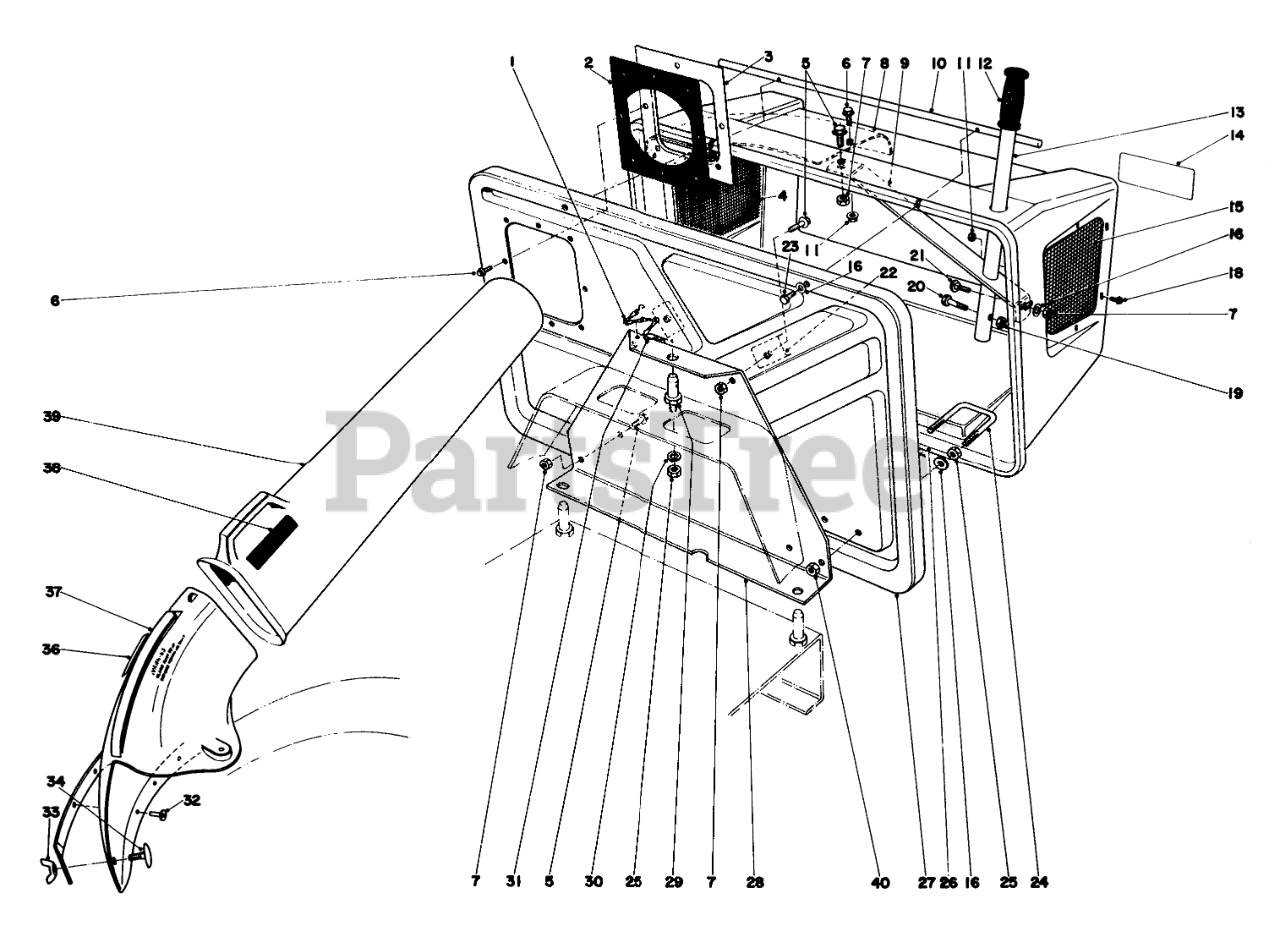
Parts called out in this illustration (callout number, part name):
1	6-LINK CHAIN W/HOOK
2	INLET SEAL
3	FRAME SEAL
4	Screen
5	SCREW-HHF
6	SCREW
7	NUT-HEX, SIDE DEFORM
8	DEFLECTOR
9	HANDLE GUIDE
10	PIVOT ROD
11	NUT-LOCK, FLANGE
13	HANDLE TUBE
14	EASY EMPTY BAG DECAL
15	SCREEN
16	WASHER-FLAT
18	SCREW-HWH
19	NUT-HEX, SIDE DEFORM
20	SCREW-HH
21	SCREW-CARR
22	Retainer
23	SCREW-HH
24	LATCH
25	NUT-HEX
26	HOPPER
28	Plate Mounting
29	Pin-Mounting
30	WASHER-LOCK
31	HAIRPIN COTTER
32	Pop Rivet
33	NUT-WING
34	STEP BOLT
36	Decal-Chute
37	Chute Assembly (Incl. Ref. #32 & 35-36)
38	Decal Duct
39	Duct Assembly (Incl. Ref. #38)
40	NUT-LOCK, NI
